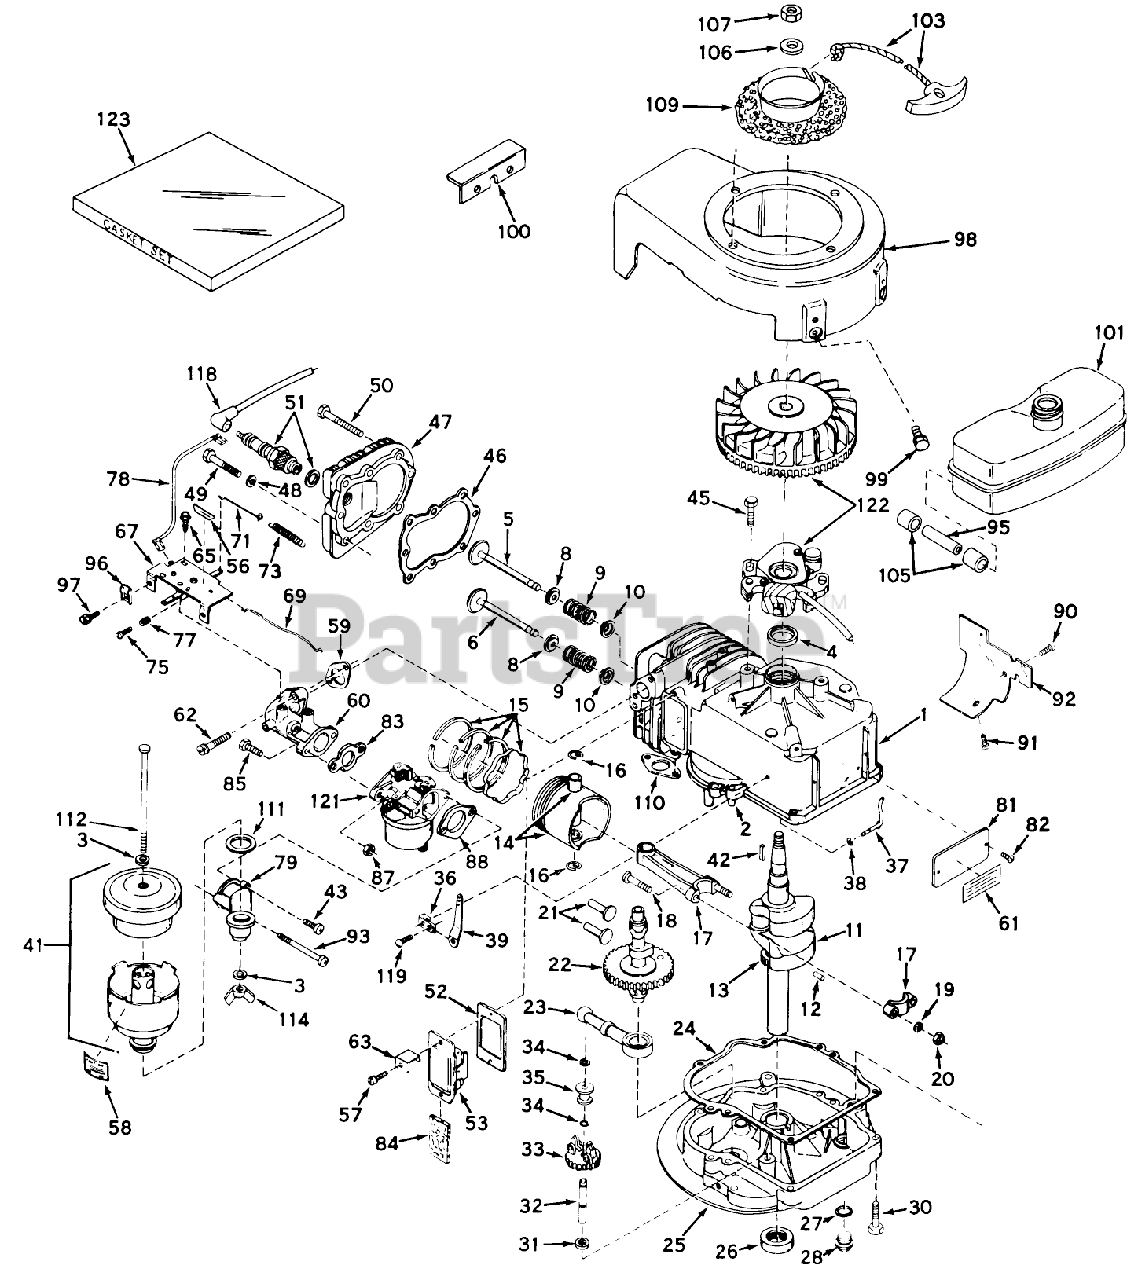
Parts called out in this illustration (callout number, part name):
1	Cylinder Assy. (Incl. Ref. 2 4)
2	Pin-Dowel
3	Washer Fibre
4	OIL SEAL
5	Valve, Intake (Incl. Ref. #38, 39 40) (Std.)
5	Valve, Intake(1/32"overs.)(Incl. Ref. 8, 9 10)
6	Valve, Exhaust (Standard)(Incl. Ref. 8, 9 10)
6	Valve, Exhaust (1/32" Overs.(Incl. Ref. 8, 9 10)
8	Cap-Upper Valve Spring
9	Spring-Valve
10	Cap-Valve, Spring
11	Crankshaft Assy. (Incl. Ref. 12 13)
12	Pin, Groove
13	Gear, Crankshaft
14	Piston Pin Assy. (Incl. 2 of No. 16)(Standard)
14	Piston Pin Assy. (Incl. 2 of No. 16)(.010 oversize)
14	53020 ADN. TO 28594
15	Piston Ring Set Std.
15	Piston Ring Set .010 O.S.
15	Piston Ring Set .020 O.S.
16	Ring-Retaining, Piston Pin
17	Rod Assy., Connecting (Incl. Ref. #17)
18	Bolt, Connecting
19	Washer
20	LOCKNUT
21	Lifter-Valve
22	Camshaft
23	Oil Pump ASM
24	Gasket, Mounting
25	Flange Assy., Mounting (Incl. Ref. 26, 27, 28 32)
26	Seal Oil
27	Gasket-Oil Drain
28	Plug Oil Drain
30	Screw (1/4-20 x 1-1/4)
31	Washer-Flat
32	Shaft-Governor
33	Governor Gear ASM
34	Ring-Retaining
35	Spool-Governor
36	Clamp-Lever, Governor
37	Rod, Governor (Incl. No. 36)
38	Washer-Flat
39	Lever, Governor
41	Cleaner Assy., Air
42	Key Flywheel
43	KIT - SEAL WIPER
45	Screw
46	Gasket-Cylinder Head
47	CYLINDER HEAD
48	Washer
49	Screw
50	Screw
51	SPARK PLUG
52	Gasket Breather
53	Breather Assembly (Incl. Nos. 52 84)
56	Decal
57	Screw
58	Decal, Air Cleaner
59	Gasket, Intake
60	Pipe, Intake
61	480B GIL SNWTHWR O/
62	Screw, Fil. Hd. Sems
63	Retainer Clip
65	Screw (10-24 x 9/16)
67	Control Assy., Speed
69	Link, Throttle to Governor
71	Link, Governor Spring
73	Spring, Governor
75	Screw
77	Spring-Compression
78	Wire, Ground
79	Elbow, Air cleaner
81	IDENTIFICATION PLATE
82	Stud
83	Gasket
84	Element-Breather
87	Nut and Lock Washer (1/4-28)
88	Gasket
90	Screw
91	Screw
92	Extension, Housing
93	Screw
95	Line, Fuel
96	Conduit
97	Screw (10-32 x 3/8)
98	Housing, Blower
99	Screw (1/4-20x19/32)
100	Bracket, Shroud
101	Tank, Fuel
103	Rope Assy., Starter
105	Line-Fuel (8.62)
106	Washer
107	Hex Nut
109	Pulley, Rope Start
110	Gasket Exhaust
111	Gasket, Spacer
112	Bolt, Air Cleaner
114	Nut, Wing
118	Cover-Spark Plug
119	Screw
121	Carburetor
122	Magneto
123	Gasket Set
